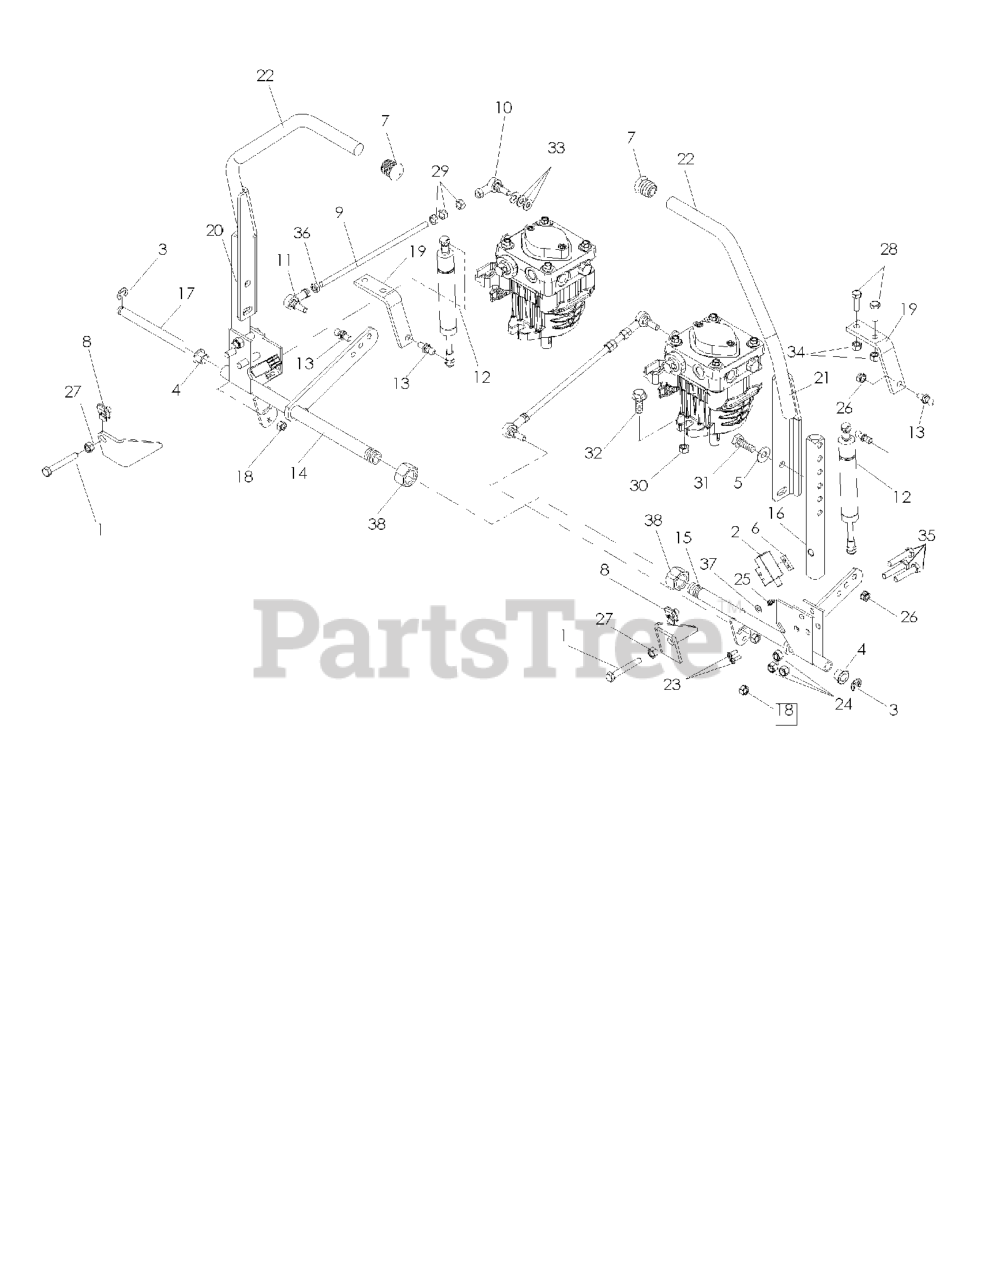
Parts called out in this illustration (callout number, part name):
1	BOLT HEX 1/4 X 1-1/4
2	SWITCH, INTERLOCK
3	E-RING 1/2 (2 2)
4	BUSHING
5	WASHER, 3/8 DISC SPRING SPEC
6	TAPPED PLATE
7	END PLUG 15/16` (BLACK)
8	U-CLIP 5/16-18 NUT RETAINER
9	PUMP CONTROL LINK
10	SPHERICAL ROD END, RH
11	SPHERICAL ROD END, LH
12	DAMPENER
13	STUD.BALL.10MM
14	CONTROL ASM - ADJ, RT
17	CONTROL SHAFT
18	NUT 5/16F NYLOC
19	DAMPENER BRACKET
20	LEVER, DRIVE, RT
21	LEVER, DRIVE, LT
22	GRIP, FOAM (GROUND) 15
23	SCREW #10-24 X 5/8
24	NUT 3/8-16 NYLOC
25	ZERK
26	NUT 5/16C CENTERLOCK
27	NUT 5/16C HEX
28	HCS 5/16C X 1
29	NUT 5/16F
30	NUT 3/8C CENTERBLOCK
31	HCS 3/8C X 1
32	HCS 3/8C X 1 SERRATED HEAD
33	WASHER 5/16 FLAT
34	NUT 5/16 NYLOC
35	HCS 3/8-16 X 1 3/4 GR5
36	NUT 5/16F LEFTHAND
38	NUT 3/4 X 16 HEX CTR
